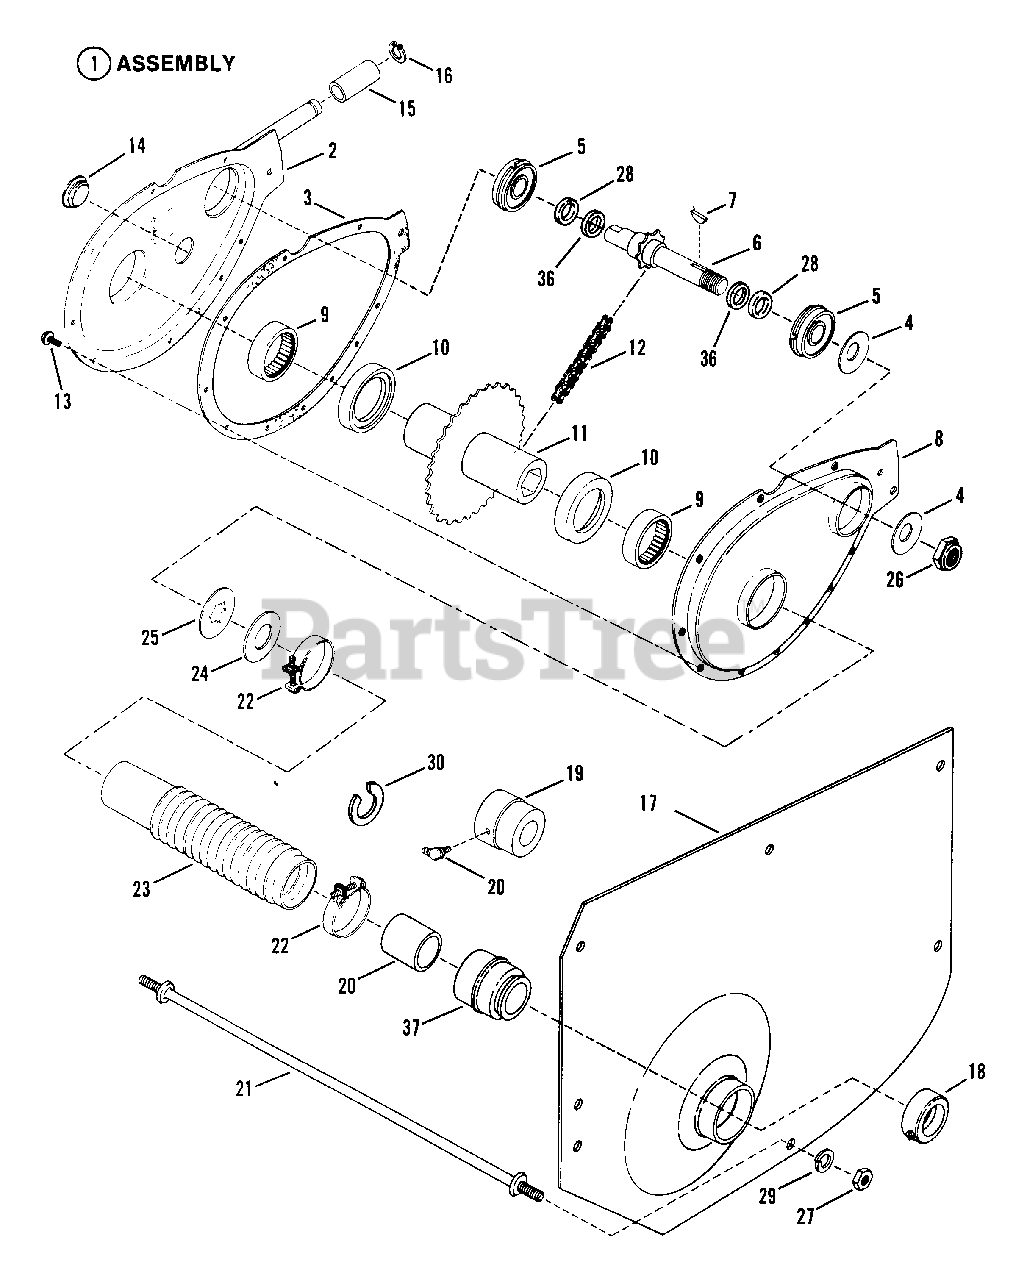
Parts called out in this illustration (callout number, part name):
1	ASSEMBLY, Chain Case
2	CASE, Sprocket
3	GASKET, Case Cover
4	WASHER, Belleville
5	BEARING, Ball
6	SPROCKET & SHAFT
7	KEY, 1/8 x 5/8" Woodruff
8	COVER, Chain Case
9	BEARING, Needle
10	WASHER, Nylon Thrust
11	HUB & SPROCKET
12	CHAIN
13	SCREW, #10-24 x 1/2" Hex Washer Self-Tap (Torx)
14	PLUG, Oil Fill & Check
15	ROLLER
16	RING, Retaining
17	FENDER, Left Hand
18	COLLAR, Lock
19	BEARING, Left Hand Fender
20	FITTING, Lube
20	Spacer (for ball bearing)
21	ROD, Cross-Tie
22	CLAMP, Boot
23	BOOT, Oil Seal
24	WASHER, Thrust Nylon
25	WASHER, Thrust
26	NUT, 5/8-18 Hex Lock
27	NUT, 5/16-24 Hex
28	O-RING
29	WASHER, 5/16 Split Lock
30	WASHER, Shim
36	WASHER, Shim
37	BEARING, Left Hand Fender
37	ASSEMBLY, Left Hand Fender
